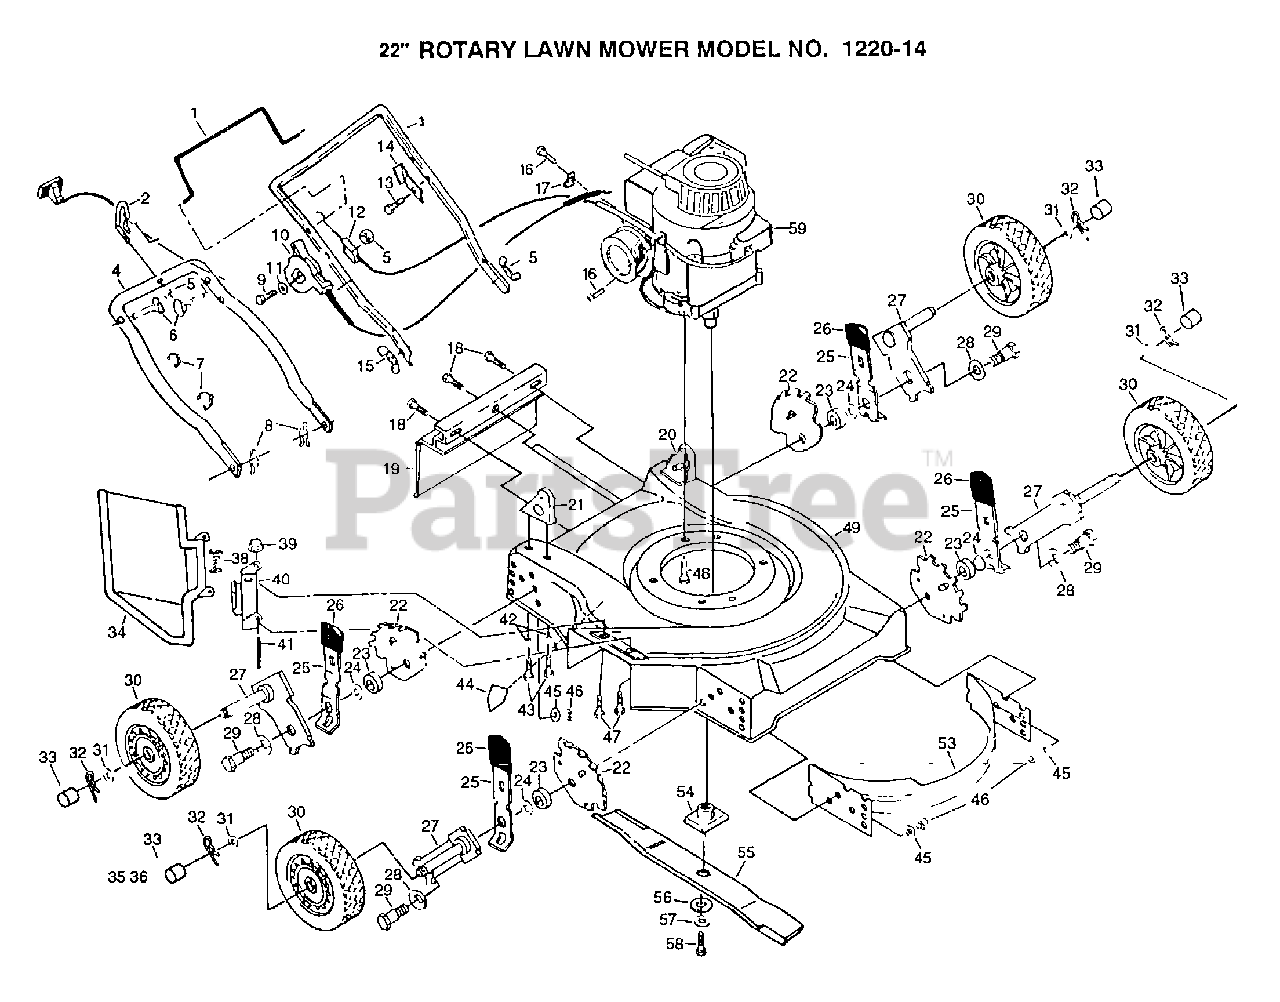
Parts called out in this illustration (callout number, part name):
1	CONTROL BAR PM
2	ROPER GUIDE PM
3	"HANDLE,UPPER "
7	CABLE CLIP PM
8	HAIRPIN COTTER
10	CONTROL.THROTTLE
11	WASHER PM
13	TAPPING SCREW
14	"BRKT,UPSTOP"
15	"NUT,WING PM"
16	SCREW PM
17	CABLE CLAMP
18	SCREW
19	REAR SKIRT M
24	WASHER PM
26	KNOB PM
27	AXLE ARM
28	"WASHER, BELLEVIL."
30	WHEEL.ASM
31	WASHER
32	RETAINER CLIP PM
33	HUB CAP-PLASTIC
38	"SPRING,TORSION"
39	PUSH ON SPEED NUT
40	"BRKT,HSG"
41	"ROD,HINGE "
42	STEEL WASHER
43	SCREW
44	DECAL HYT
46	LOCKNUT PM
47	SCREW
54	BLADE ADAPTOR
55	"BLADE.22"""
56	"WASHER,HARDEN"
57	LOCKWASHER
58	SCREW
